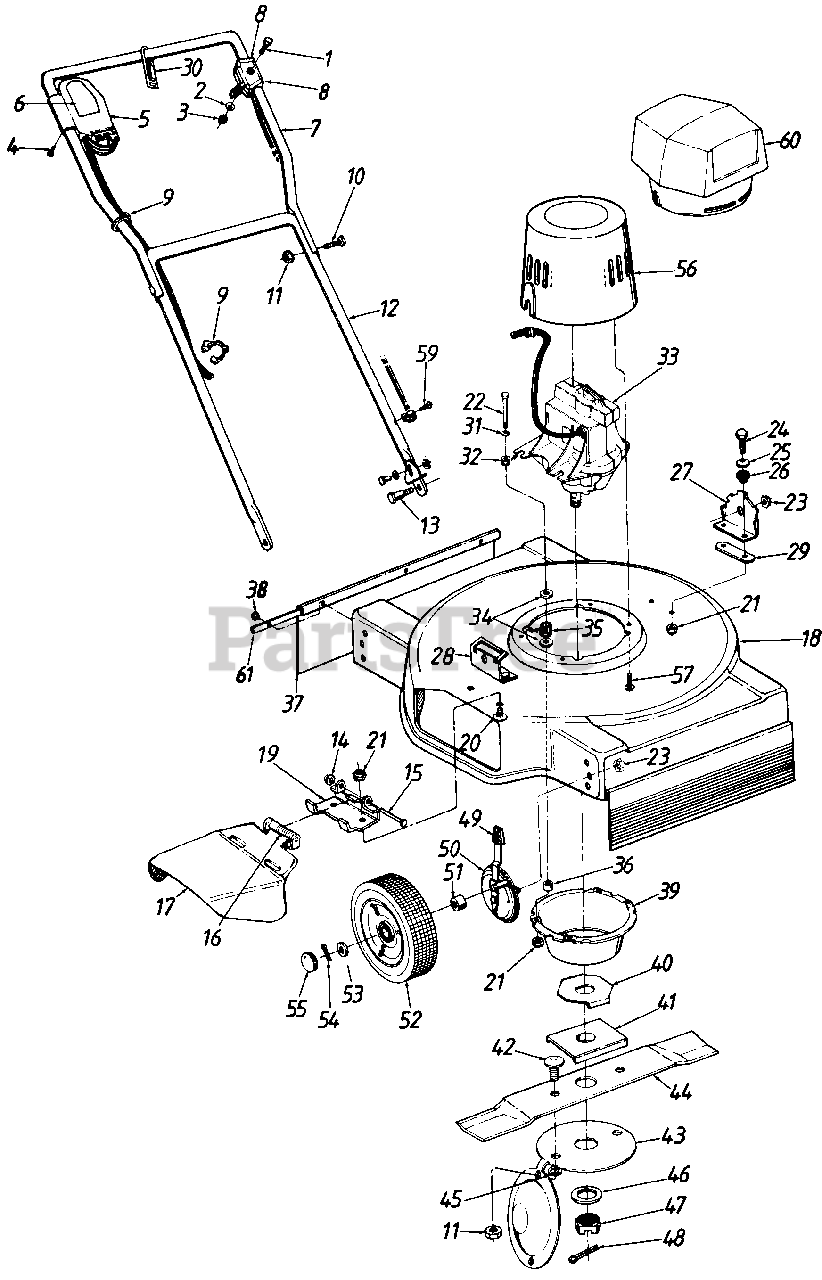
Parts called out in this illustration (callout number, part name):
1	Hex Bolt 1/4-20 x 1.5"
2	Washer
3	Acorn Nut 1/4-20 Thd.
4	Hi-Lo Screw #7 x 1"
5	Cord & Switch Box Comp.
6	Label-Switch Box
7	Upper Handle
8	Cable Release Control
9	Cable Tie
10	Hex Bolt 5/16-18 x 11/4" Lg.*
11	Hex Sems Nut 5/16-18 Thd.
12	Lower Handle Ass'y.
13	Shoulder Bolt
14	Cap Speed Nut 1/4" I.D.
15	Hinge Pin
16	Torsion Spring
17	Chute Deflector Ass'y.
18	19" Deck Ass'y.
19	Adapter Plate
20	Carriage Bolt 1/4-20 x 5/8" Lg.
21	Hex L-Nut 1/4-20 Thd.
22	Hex Bolt 1/4-20 x 21/2" Lg. (Grade 5)
23	Hex Sems Nut 3/8-16 Thd.
24	Hex Bolt 1/4-20 x 7/8"
25	Fl-Wash. 1/4" I.D.
26	Insulator
27	Handle Bracket-L.H.
28	Handle Bracket-R.H.
29	Insulator Strip
30	Cord Restraint
31	Fl-Wash. 1/4" I.D. x 3/4" O.D.
32	Insulator
33	Motor & Switch Ass'y. Comp.
34	Fl-Wash. 1/4" I.D. x 1" O.D.
35	Grommet Ass'y.
36	Spacer
37	Flap-Rear & Front
38	Rivet
39	Motor Shield
40	Blade Adapter
41	Adapter Insulator
42	Carriage Bolt 5/16-18 x 3/4" Lg.
43	Blade Insulator
44	19" Blade
45	Bolt Retainer
46	Fl-Wash. 1/2" I.D.-H.T.
47	Castle Nut 1/2 " I .D.
48	Cotter Pin
50	Height Adj. Ass'y.
51	Spacer
52	7" Wheel Ass'y.
53	Fl-Wash. 1/2" I.D.
54	Cotter Pin
55	Hub Cap
56	Motor Cover
57	Self-Tap Scr. #10-16 x 3/4" Lg
59	Screw
60	Motor Cover
